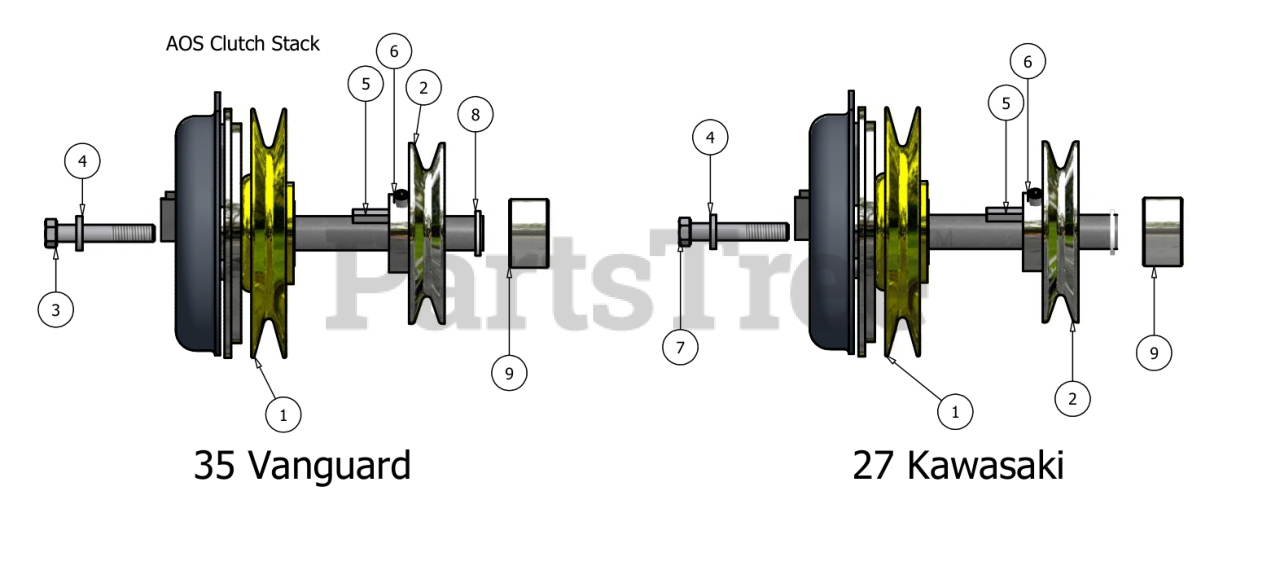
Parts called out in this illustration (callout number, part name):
1	Clutch Assembly
2	4 3/4" Motor Pulley
3	7/16" x 2 1/2"Fine Thread Bolt
4	7/16" Lock Washer
5	1/4" x 1" Key
6	3/8" Set Screw
7	10mm x 552 Bolt
8	1 1/8" Flat Spacer
9	1 1/8 collar spacer
